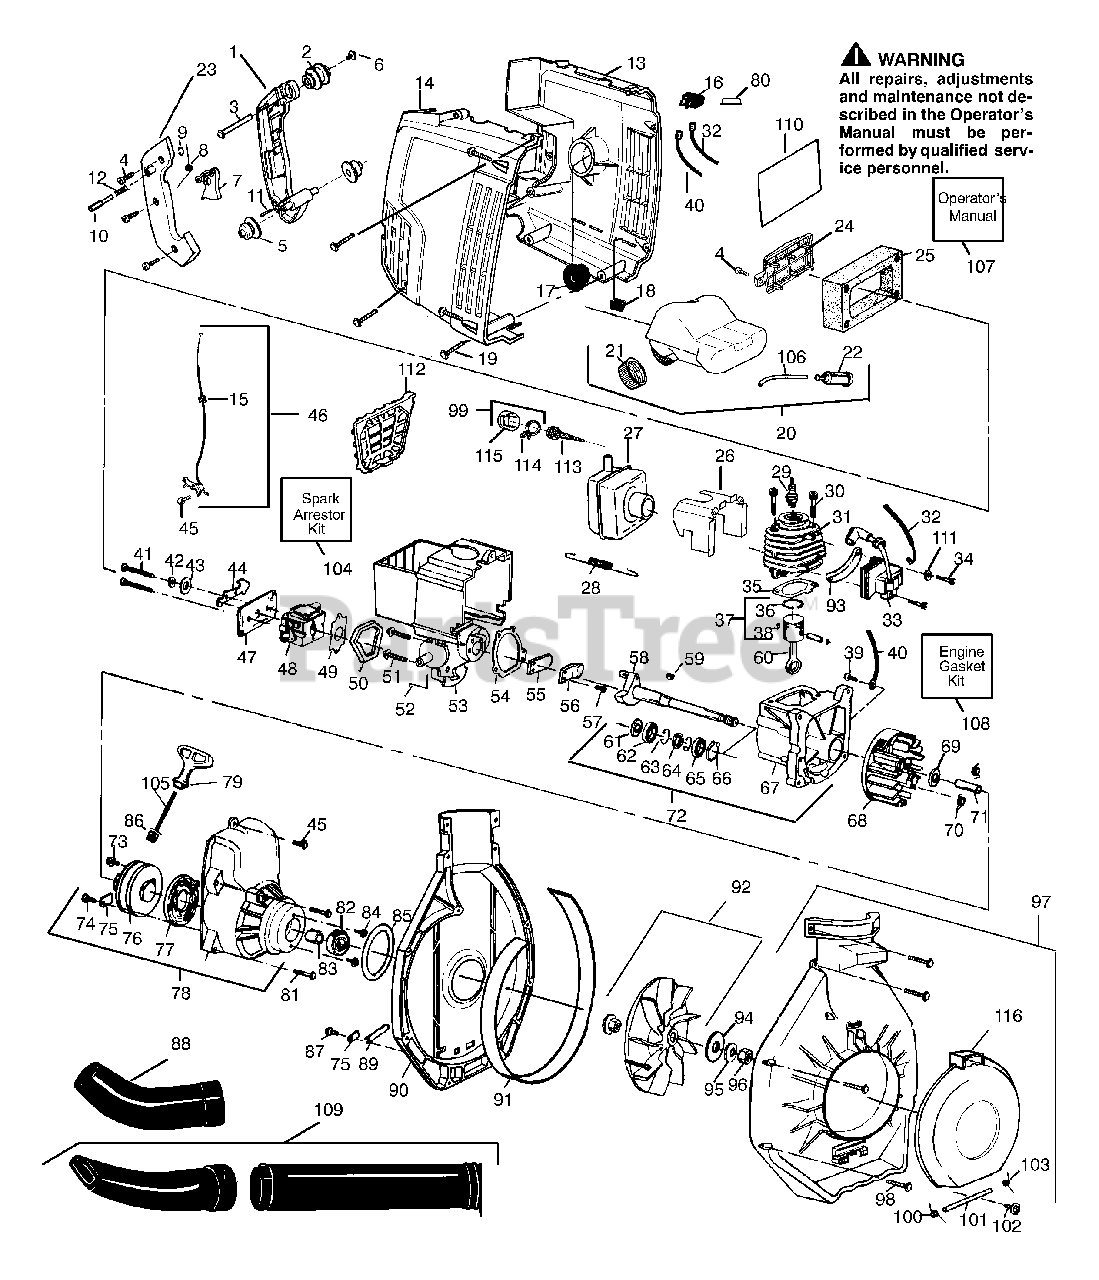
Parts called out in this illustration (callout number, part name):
1	Handle
2	Front Isolator
5	Rear Isolator
9	"C" Clip
10	Throttle Lock Button
13	Shroud-Left
14	Shroud-Right
17	Isolator
18	Isolator
20	Fuel Tank Ass'y.
21	Fuel Cap
22	Fuel Pick-up Ass'y.
23	Handle Cover Ass'y.
25	Air Filter
26	Air Baffle
29	Spark Plug
31	Cylinder
31	30V - Type 1
31	30 V - Type 2 & 3
32	Lead Wire
33	Ignition Module
34	Screw
35	Gasket
36	Piston Ring
37	Piston Kit
37	30V - Type 1
37	30V - Type 2 & 3
38	Retainer
40	Ground Wire
42	Wave Washer
44	Choke Shutter
46	Cable Assembly
48	Carburetor
48	Type 1 & 2 (WT 141)
48	Type 3 (WT 141A w/ Limiter Cap)
52	Ground Wire
53	Reed Block
55	Reed Valve
56	Reed Stop
58	Crankshaft
60	Piston Rod
61	Spacer
62	Inner Bearing
64	Crankshaft Seal
65	Outer Bearing
66	Retaining Ring
67	Crankcase
68	Flywheel
69	Washer
71	Spacer
72	Crankcase/Crankshaft Assy.
75	Retainer
76	Starter Pulley
77	Starter Spring
78	Fan Housing Kit
79	Starter Handle
80	Protector Cap
82	Bearing
83	Spacer
84	Screw
85	"O" Ring
88	Blower Nozzle Concentrator
89	Roll Pin
90	Blower Housing (Upper)
92	Impeller
97	Blower Housing (Lower)
98	Screw
99	Deflector & Clamp Ass'y.
104	Spark Arrestor Kit
105	Rope Kit
106	Line Kit
107	Operator's Manual
108	Gasket Kit
109	Tube and Nozzle Ass'y
110	Decal Instruction
111	Washer
112	Muffler Guard
113	Spark Arrestor Screen
114	Spark Arrestor Clamp
115	Exhaust Deflector Ass'y.
116	Inlet Door
